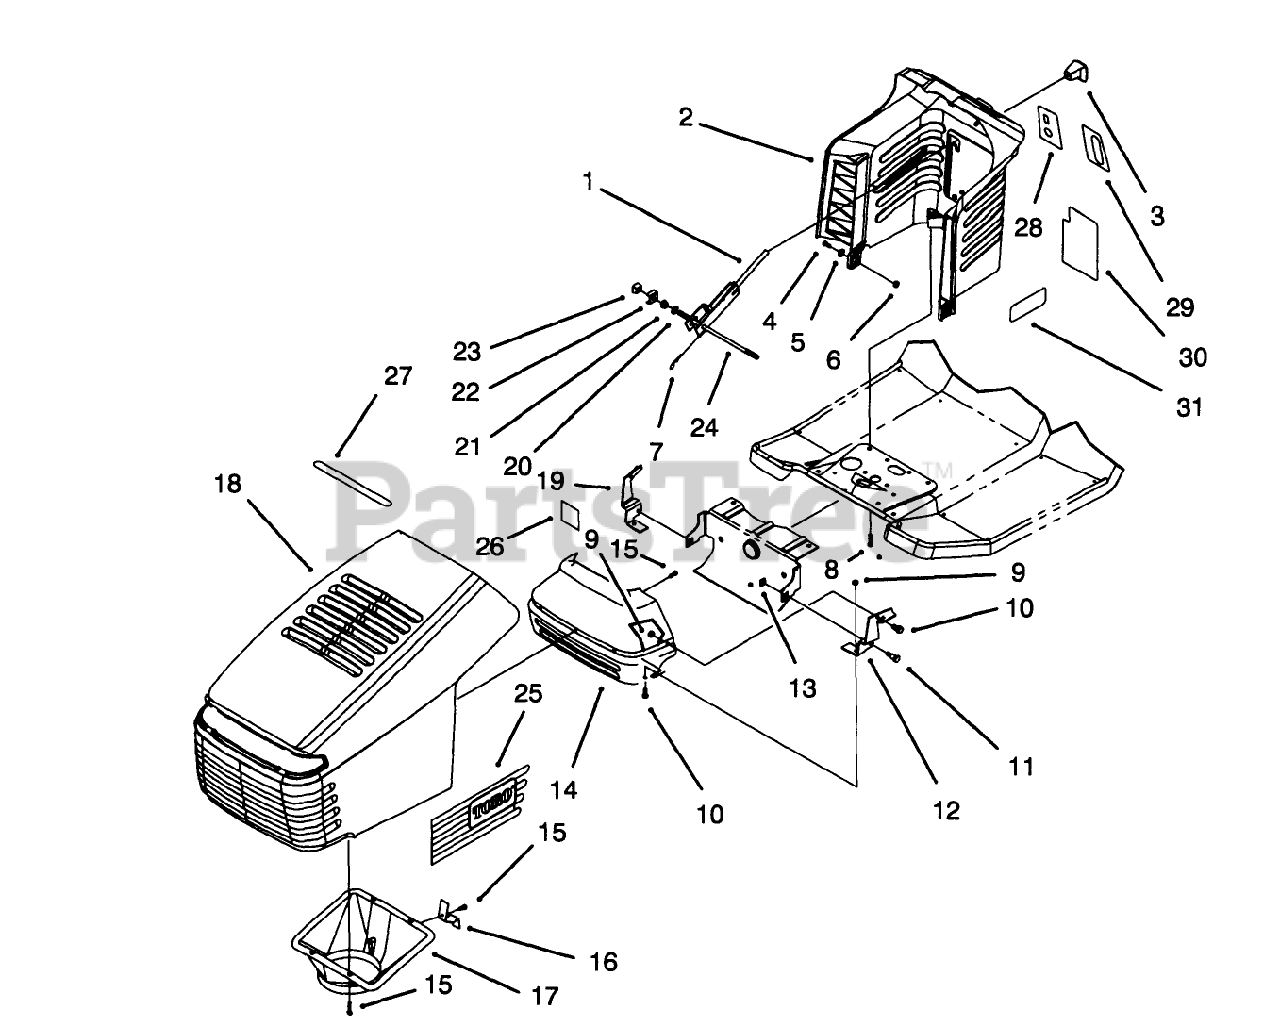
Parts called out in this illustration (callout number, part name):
3	SHIFT KNOB
4	SCREW-HH
5	WASHER-PLAIN
6	NUT-LOCK, NI
8	SCREW-HWH
9	NUT-LOCK, NI
10	SCREW-HH
11	BOLT-SHOULDER
13	NUT-RETAINER
15	SCREW-PLASTITE
16	HOOD LATCH
17	DUCT-AIR
18	HOOD ASM
20	WASHER-FLAT
21	NUT-FLANGE
22	ROD-CLAMP PIVOT
24	ROD-TOWER PIVOT
25	DECAL - HOOD LEFT
26	PICK AS EACH
27	DECAL-AIR DUCT
28	DECAL - IGNITION
29	DECAL-THROTTLE/CHOKE
30	DECAL-DECK, ENGAGE
31	DECAL-1232XL
